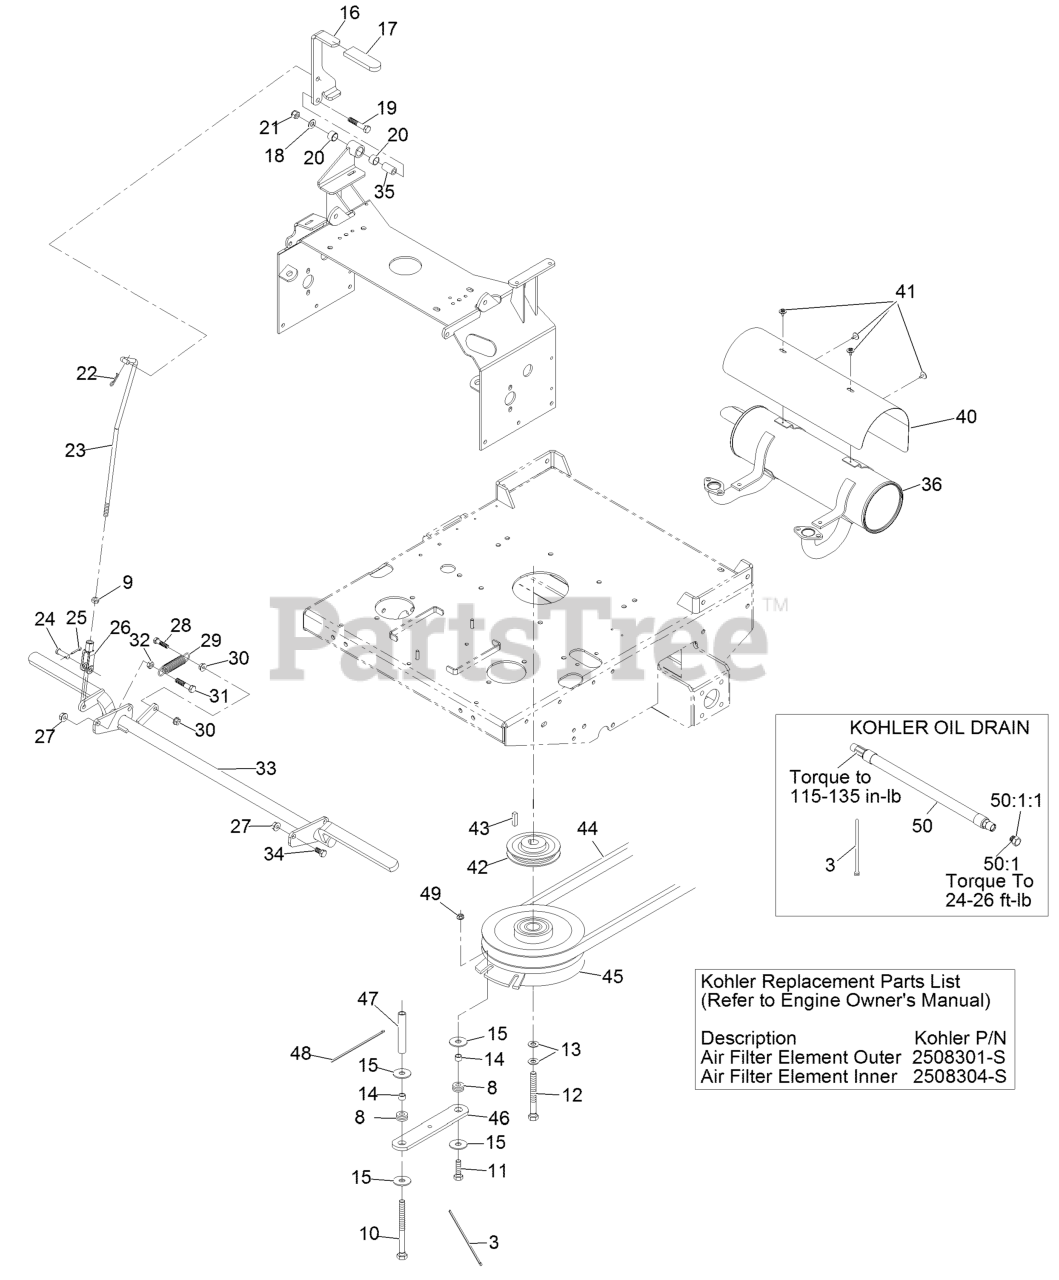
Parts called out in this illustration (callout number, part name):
3	TIE-PLASTIC
8	GROMMET
9	NUT-HJ
10	SCREW-HH
11	SCREW-HH
12	SCREW-HH
13	WASHER-SPRING
16	LEVER,PRK BRK W/DECALS
17	GRIP-LEVER
18	WASHER-FLAT
19	SCREW-HH
20	SLEEVE-BUSHING
21	NUT-LOCK, NI
22	PIN-COTTER
23	LINKAGE, PARK BRAKE
24	PIN-CLEVIS
25	PIN-COTTER
26	YOKE-LINKAGE, BRAKE
27	NUT-HHF, WHIZ
28	SCREW-HH, SPECIAL
29	SPRING-IDLER
31	SCREW-HH
32	NUT-JAM
34	SCREW-HH
35	BUSHING-PIVOT
36	MUFFLER, KOHLER 20HP
40	SHIELD, MUFFLER 20HP
41	SCREW-HH, THREAD FORMING
42	PULLEY
44	BELT,B 83.65
44	BELT,DECK DRIVE
45	CLUTCH ASM
46	STRAP-CLUTCH, BRAKE
47	SPACER,SHIELD
48	TIE-CABLE
50	OIL DRAIN HOSE ASM
50:1	PLUG-HH
50:1:1	O-RING
